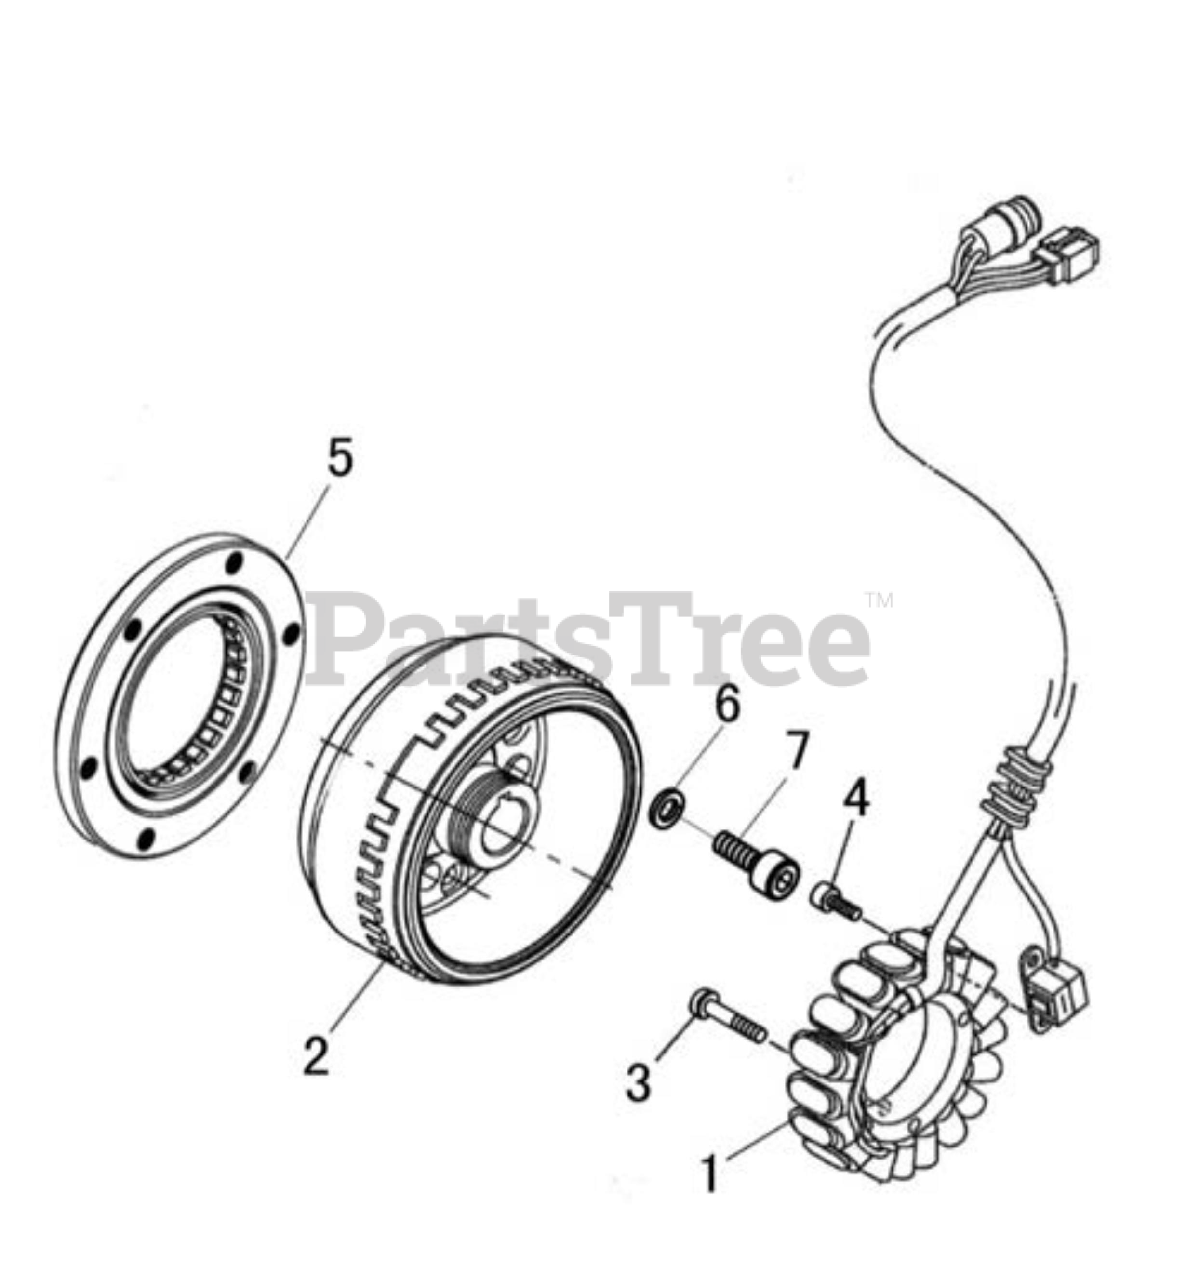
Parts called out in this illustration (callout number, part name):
1	Generator Stator Assy
2	Generator Rotor Assy
3	Hexagon head bolt and plain washer assemblies M6X30
4	Hexagon socket head cap screws M5X12
5	Overrunning Clutch
6	Spring Washer 8
7	Hexagon socket head cap screws M8X16
